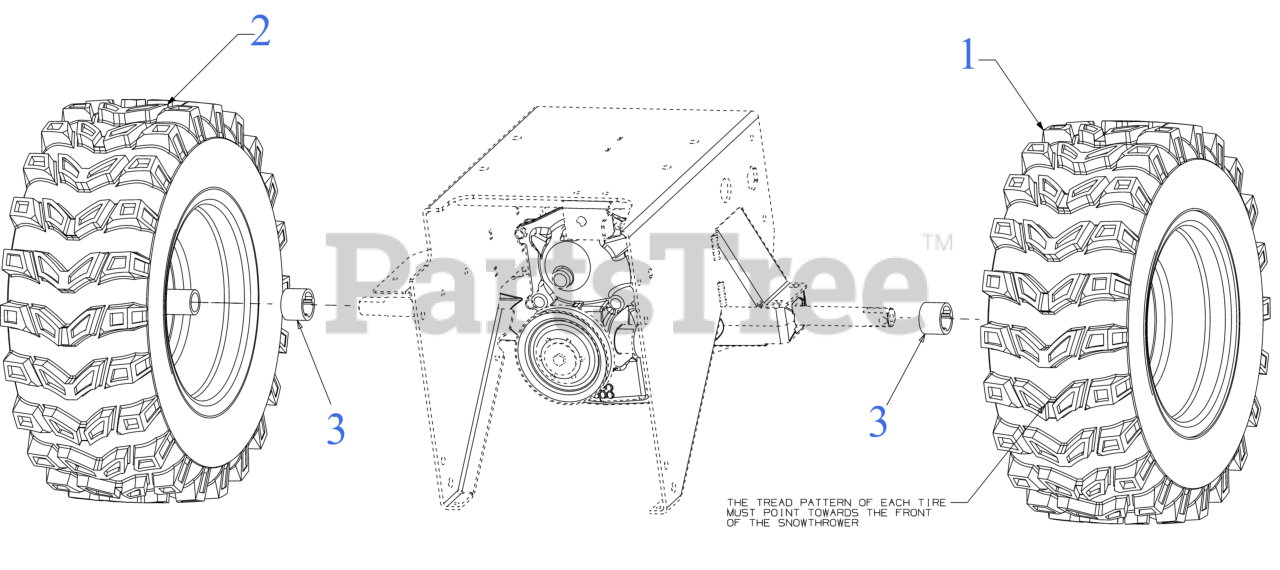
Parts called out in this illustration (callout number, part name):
1	WHEEL ASSEMBLY (16 x 6.5 x 8) (LH)
2	WHEEL ASSEMBLY (16 x 6.5 x 8) (RH)
3	SPACER 1.25 x .75 x .906
